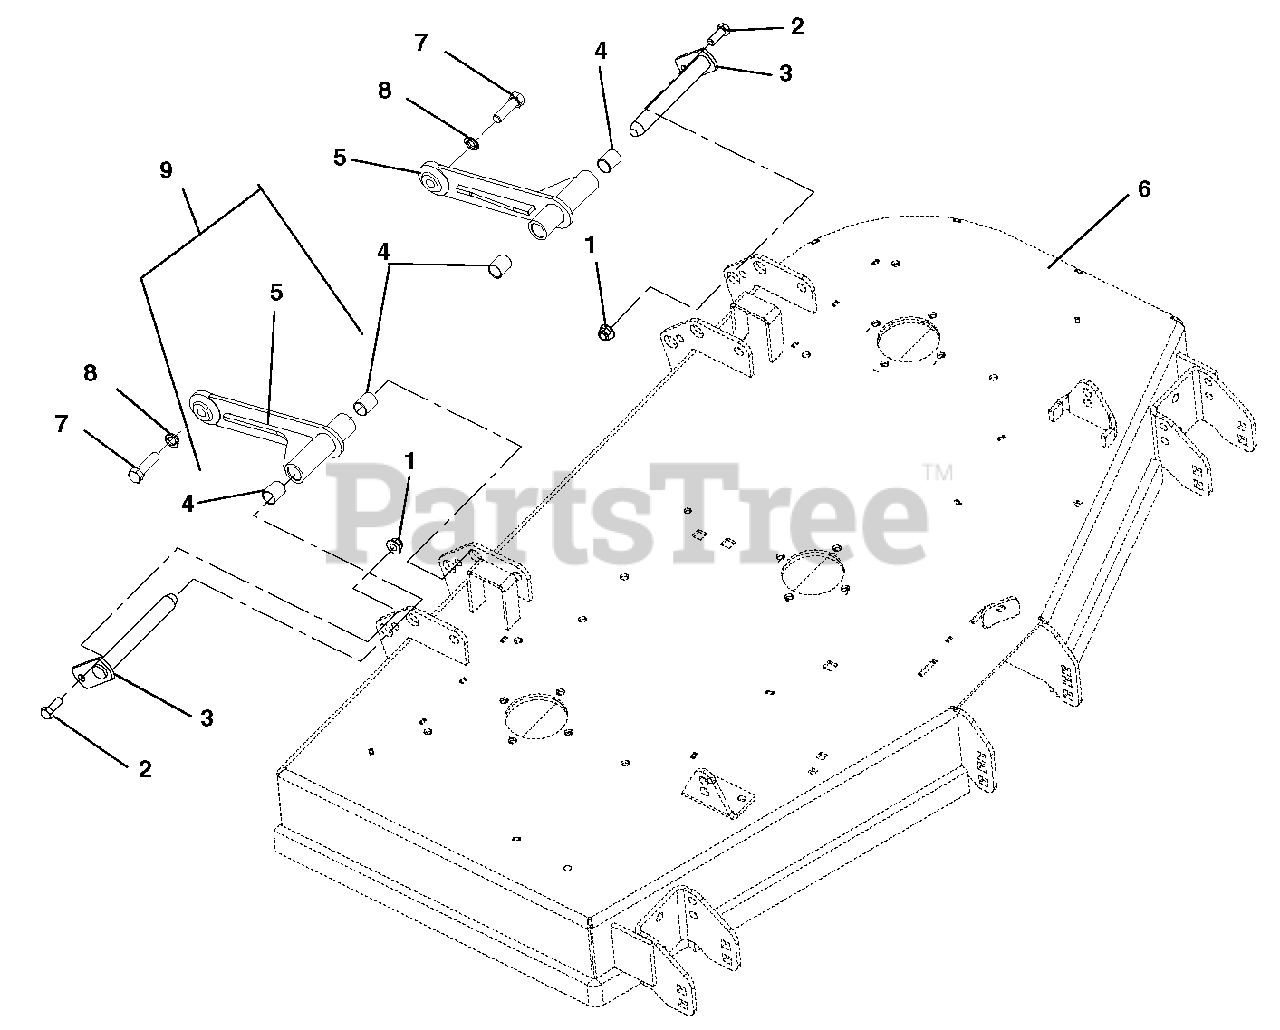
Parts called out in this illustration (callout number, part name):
1	Nut, .38-16 Nyloc Flange
2	Bolt, Hex .38-16X1.00 Grade 5
3	Weldment, Mower Mounting Pin
4	Bearing, .75 x .875 x 1.00
5	Deck Pusher Arm Weldment
6	48" 100I Rear Discharge Deck
7	Bolt, Hex .50-13 x 1.75 Grade 5
8	Washer, Locking .50 x .125 Regular
9	Assembly, Mower Mount Arm (Includes items 4 and 5)
